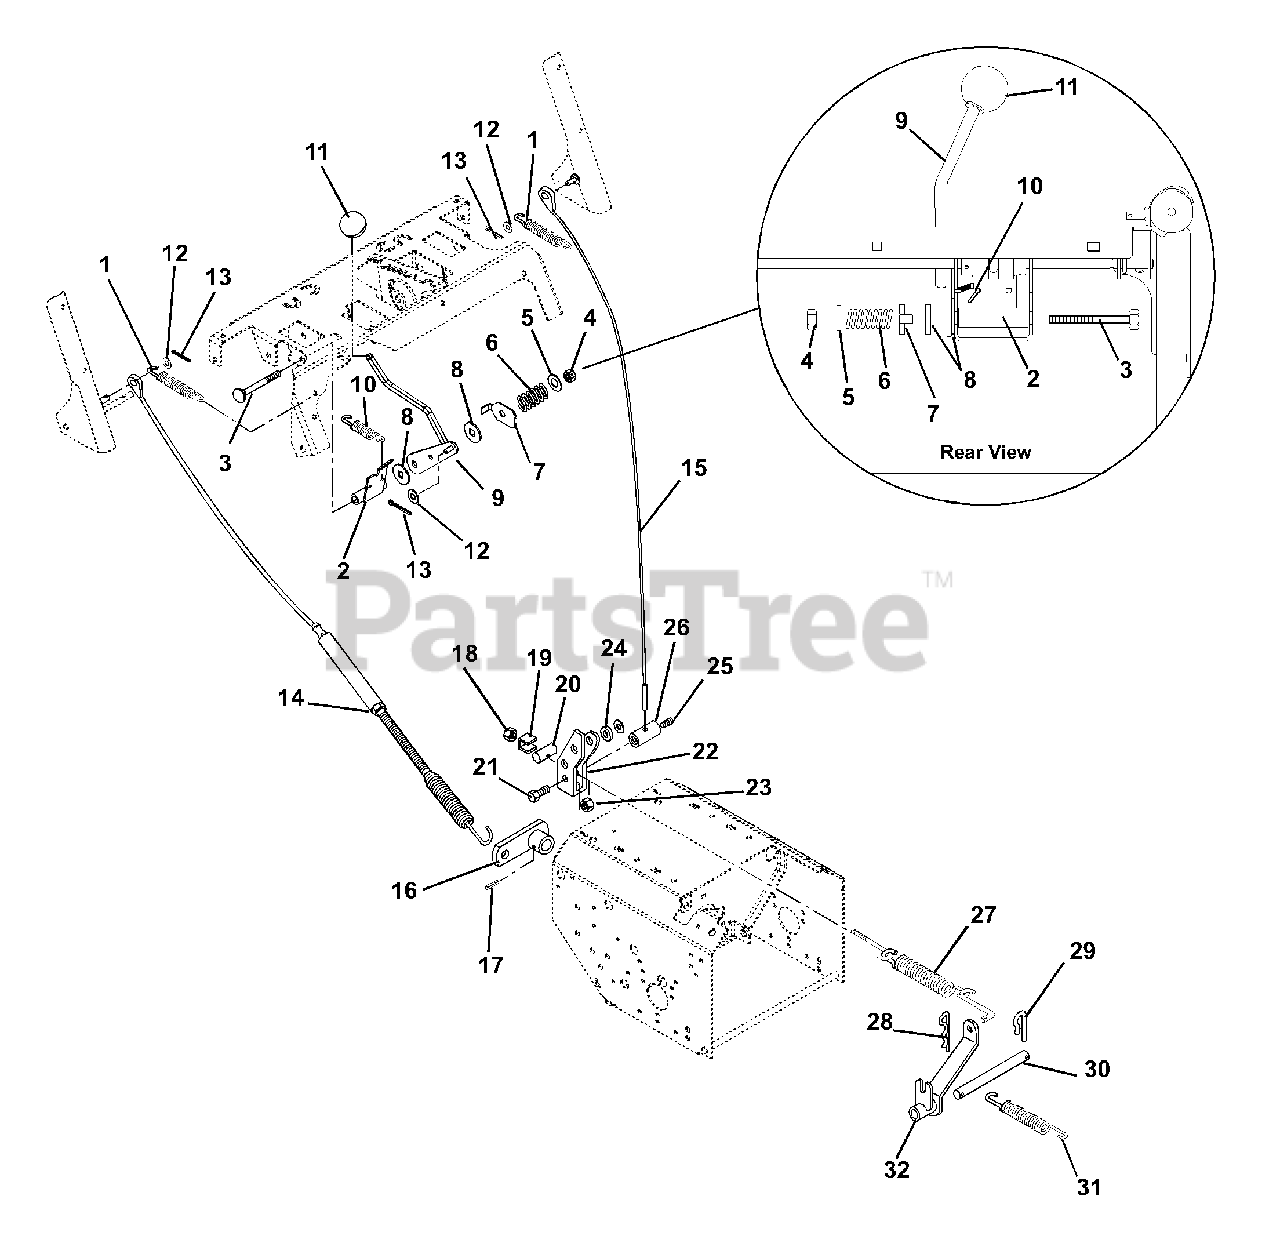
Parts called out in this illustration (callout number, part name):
1	SPRING-EXT .056X.50X3.76
2	ARM, INTERLOCK
3	@BLT-HEX .38-16X4.50 GR5 YWZC
3	@BLT-HEX .38-16X3.00 GR5 YWZC
4	@NUT-LK-CTR .38-16 YWZC
5	@WSHR-FL-STL.406X.812X.065 YWZ
6	SG-COMP .187X.56X1.62
7	PRESSURE FLANGE
8	FRICTION WASHER
9	LEVER, DEFLECTOR
10	SPRING-EXT .047X.438X1.45
11	KNOB,BALL -BLACK 1.47" .375-16
12	@WSHR-FL-STL.281X.62X.065 YWZC
13	@PIN-CTR .09X.50 EXTPRSQCT YWZ
14	CABLE, AUGER
15	CABLE, TRACTION
16	LEVER, CLUTCH
17	PIN-ROLL .156X.88
18	@NUT-LK-NYL .312-18 YWZC
19	ADAPTER SPACER
20	ADAPTER
21	@BLT-HEX .31-18X.75 GR5 YWZC
22	CLUTCH ENGAGEMENT YOKE
23	@NUT-LK-CTR .31-18 YWZC
24	SPACER 1.00 X .64 X .38
25	SCR-SET .31-18X.38 SKHCUPDL
26	ROD ADAPTER
27	SPRING ASSEMBLY
28	PIN-HAIR INT .06X.18X.77
29	CLIP, SPRING
30	ROD, FORK PIVOT
31	SG-TENS .080X.73X3.06 WLD 20
32	FORK, CLUTCH
